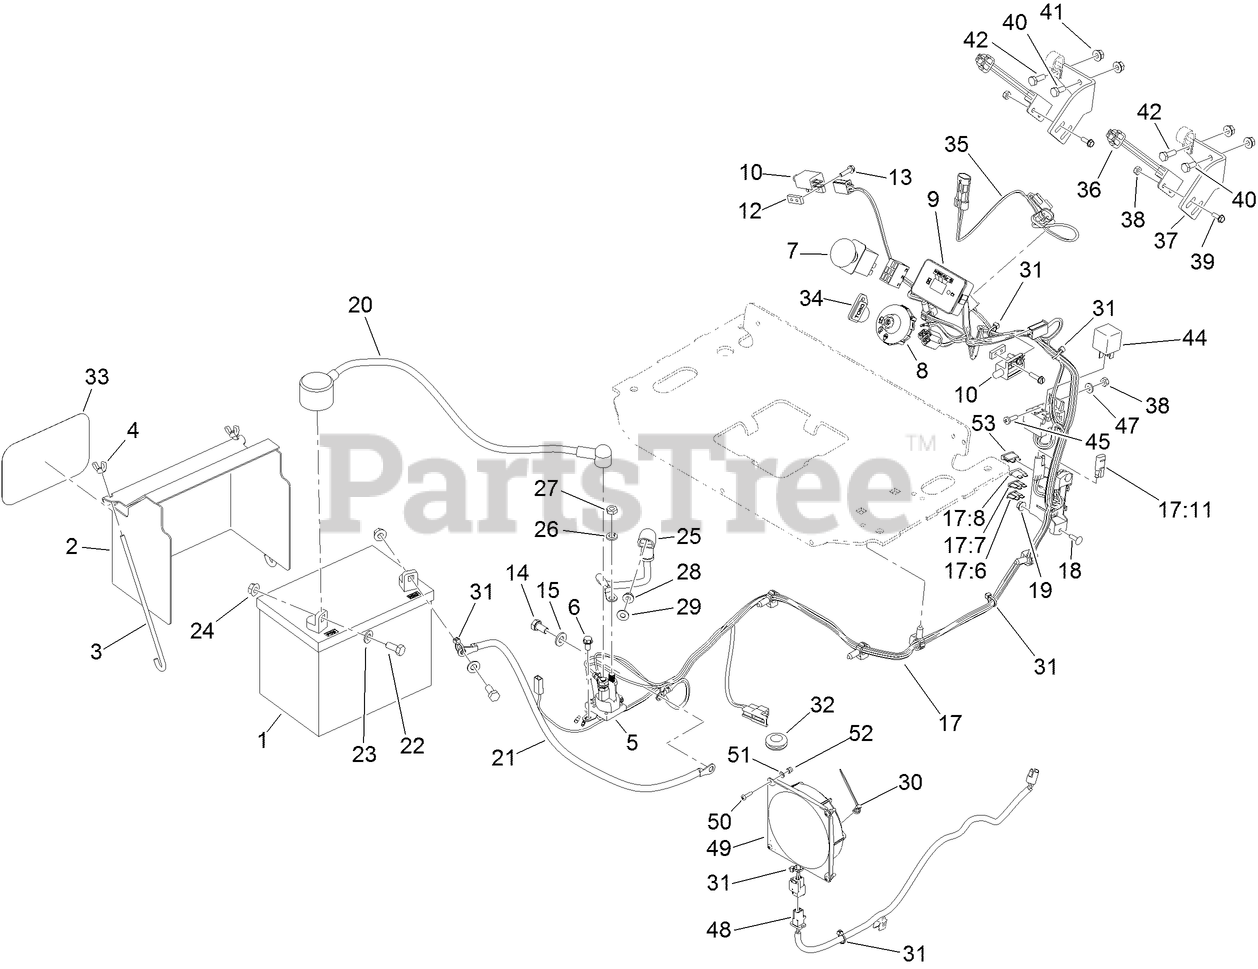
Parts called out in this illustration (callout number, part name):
1	BATTERY-DRY
2	COVER-BATTERY
3	BOLT-HOLDDOWN
4	WINGNUT
5	SOLENOID
6	SCREW-HWH
7	SWITCH-PTO, ON-ON-(ON)
8	SWITCH-IGNITION
9	MODULE-HOUR METER
10	SWITCH-CLOSED, NORMALLY
12	PLATE-TAPPED
13	SCREW-HWH
14	SCREW-HH
15	WASHER-PLAIN
17	HARNESS-WIRE
17:6	FUSE-BLADE, 30 AMP
17:7	FUSE-BLADE, 25 AMP
17:8	FUSE-BLADE, 10 AMP
17:11	CAP-PLUG
18	BOLT-CARR
19	NUT-HF
20	CABLE-BATTERY, POSITIVE
21	CABLE-BATTERY, BLACK
22	SCREW-HH
23	WASHER-PLAIN
24	NUT-HHF, SMOOTH
25	CABLE-BATTERY, RED
26	WASHER-LOCK
27	NUT-JAM
28	NUT-HF
29	WASHER-FLAT
30	TIE-CABLE
31	TIE-CABLE
32	GROMMET
33	DECAL
34	KEY-IGNITION
35	HARNESS-WIRE, NEUTRAL SWITCH
36	SWITCH-PROXIMITY
37	BRACKET-MOUNT, SWITCH
38	NUT-LOCK, NI
40	SCREW-HH
41	NUT-HHF
42	SCREW-HH
45	SCREW-PPH
47	WASHER-FLAT
48	HARNESS-WIRE, FAN
49	FAN-ELECTRIC
50	SCREW-PPH
51	WASHER-FLAT
52	NUT-LOCK
53	FUSE-BLADE, 15 AMP
